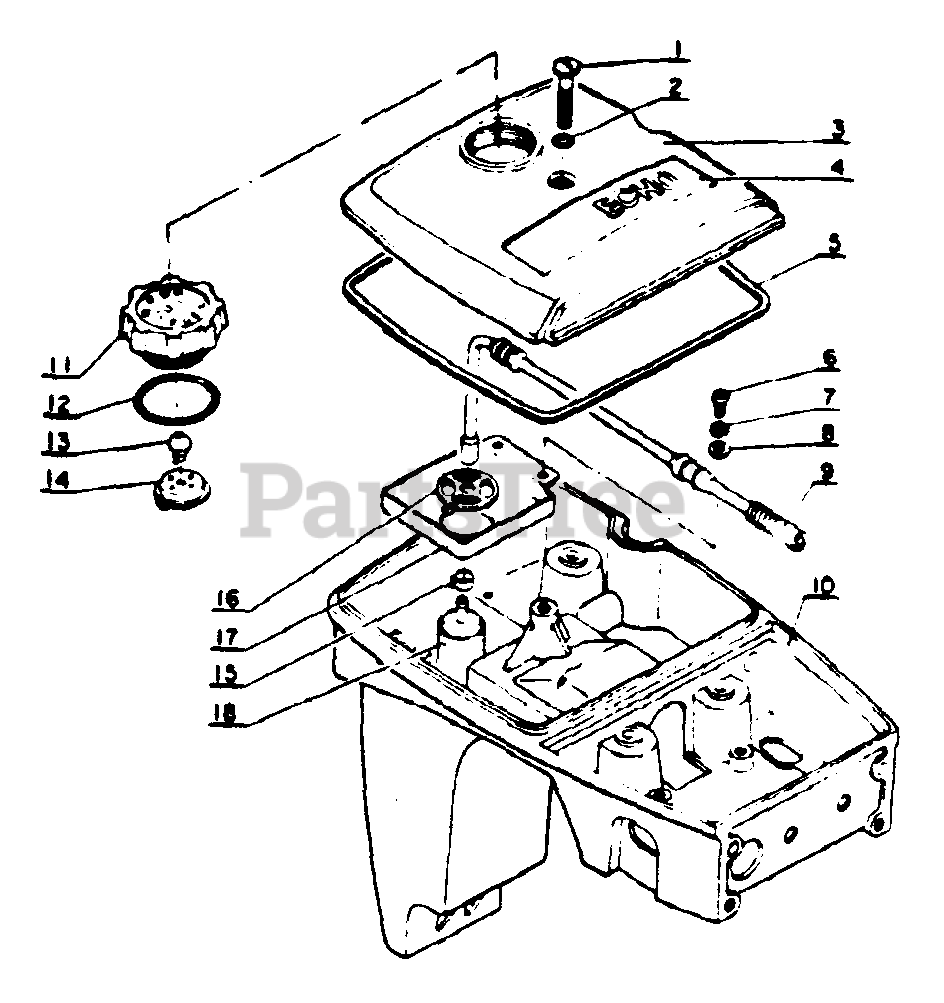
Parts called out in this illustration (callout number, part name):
1	SCREW
2	O-RING
3	LID, FUEL TANK
4	LABEL - ECHO
5	GASKET, FUEL TANK
6	SCREW - 4×10
7	WASHER, SPRING 4 MM
8	WASHER 4 MM
9	PIPE, FUEL
10	TANK, FUEL
11	CAP
12	O-RING
13	VALVE, CHECK
14	HOLDER, CHECK VALVE
15	RETAINER, PIPE
16	FUEL PIPE SPACER
17	FUEL PIPE SUPPORTER
18	FILTER, FUEL
